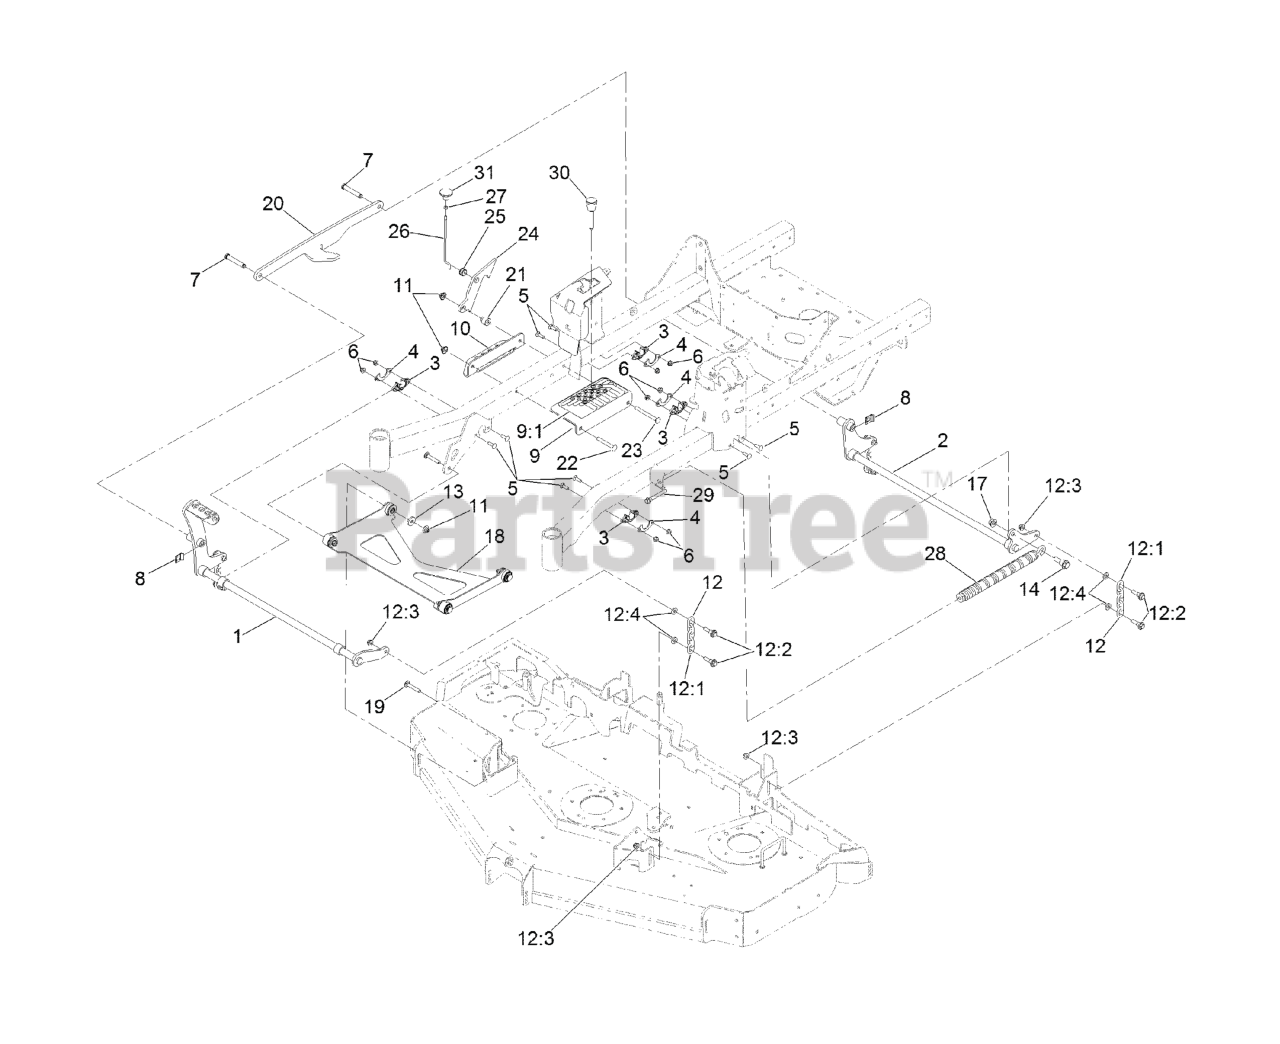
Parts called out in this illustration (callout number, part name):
1	SHAFT-LIFT, DECK
2	SHAFT-LIFT, DECK (REAR)
3	BUSHING-FLANGE
4	GUSSET-LIFT, DECK
5	SCREW-CARR
6	NUT-HF, NI
7	PIN-CLEVIS
8	CLIP-PIN
9	BRACKET ASM
9:1	DECAL-HOC
10	ANGLE-HOC, LOWER
11	Nut-Nyloc 3/8-16 Flg
12	DECK CHAIN ASM
12:1	CHAIN-LIFT, DECK
12:2	BOLT-SHOULDER
12:3	NUT-HF, NI
14	SCREW-SHOULDER, HHF 1/2-13 X 1.12
17	Nut-Lock 1/2-13
18	DECK STRUT ASM
19	Bolt-Carriage 3/8-16 X 2 1/4
20	LINK-LIFT
21	SPACER-STEPPED
22	SCREW-CARR
23	SCREW-CARR
24	PLATE-LOCK, TRANSPORT
25	GROMMET
26	ROD-LOCK, TRANSPORT
27	NUT-JAM
28	SPRING-EXTENSION
29	BOLT-SHOULDER
30	PIN-HOC
